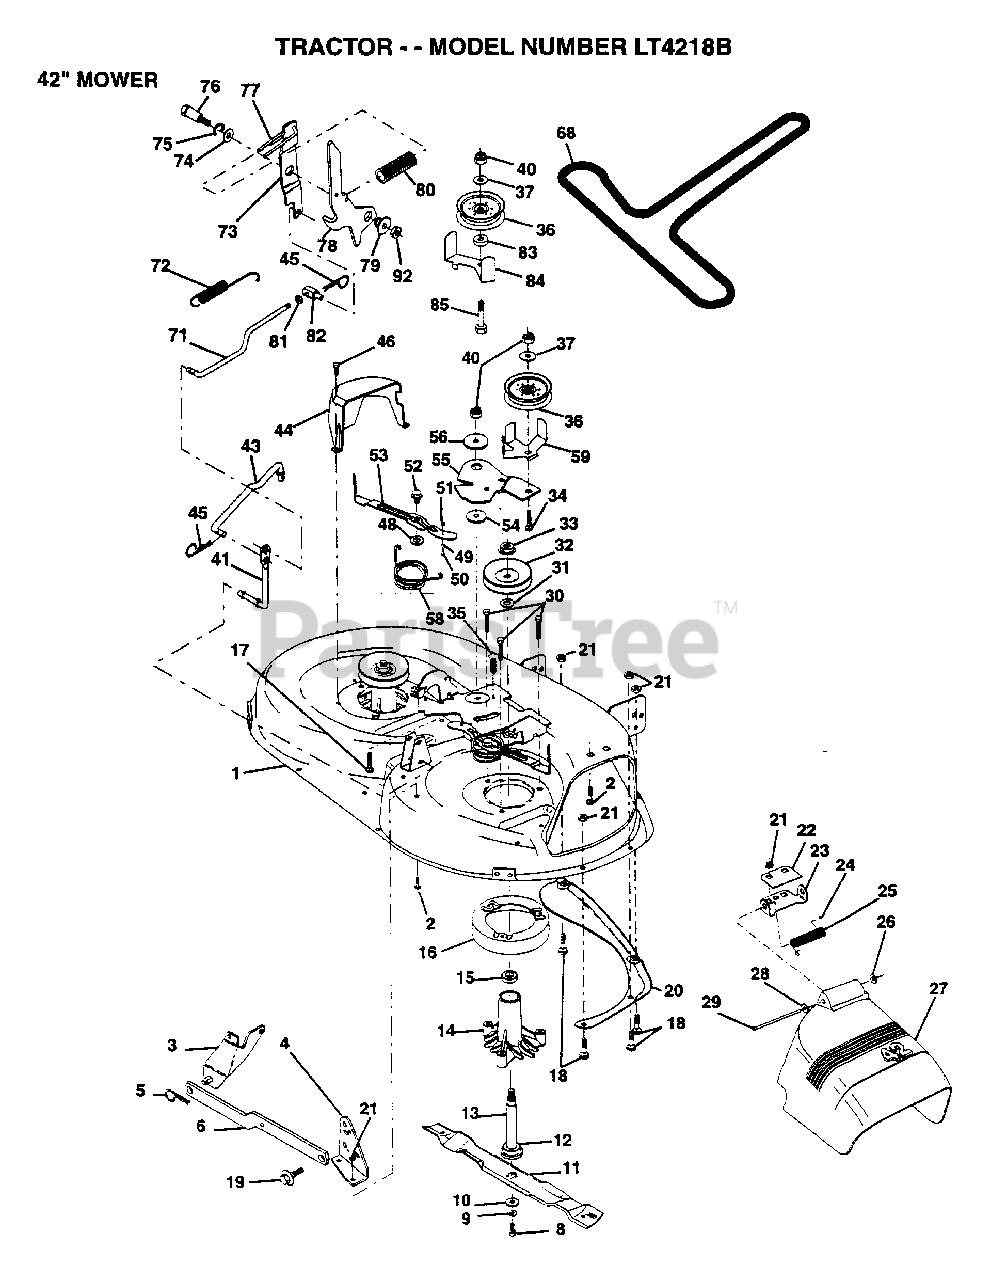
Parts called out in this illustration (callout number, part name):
1	DECK.WELD.42.
2	BOLT
3	BRKT ASM SWAY BAR
4	BRKT DECK SW BAR
8	BLADE BOLT
10	WASHER.HARD.BLADE
11	"BLADE.42"" HIPERF"
12	BEARING.BALL
14	HSG ASM MANDREL
15	BEARING
17	BOLT RDHD 3/8-16
18	BOLT
19	BOLT SHD 5/16-18
21	NUT
22	STIFFENER BRKT
23	DEFLECTOR BRKT
24	CAP-SLEEVE LT
25	SPRING TORSION
26	NUT PUSH M
27	DEFLECTOR.SHIELD
28	WASHER
29	HINGE ROD
31	WASHER
34	BOLT
35	XMAS TREE FASTNER
36	FLAT IDLER PULLEY
37	WASHER
40	NUT
41	PIVOT ROD
43	ROD CLUTCH W/NIBS
44	GUARD MAND LH BLK
45	RETAINER M
46	SCREW.1/4-20X5/8
48	HARD SMALL WASHER
50	SHOULDER BOLT
51	LOCKNUT
52	BOLT.SHLD.5/16-18
53	BRAKE PAD ARM ASM
54	HARDENED WASHER
56	SPACER RETAINER
58	SPRING TORSN BRAK
59	GUARD IDLER TUV
68	BELT-V MWR 82.625
71	ROD CLUTCH 38/42
72	SPRING EXT
73	CLUTCH ARM SECOND
74	WASHER
75	RING
76	SHOULDER BOLT
77	SPRING KEEPER
79	BUSHING
83	KNOB T (1/2-HOLE)
90	KEEPER BELT LH 42
92	SPRING TORSN BRAK
94	NUT
95	TRUNION ADJ
